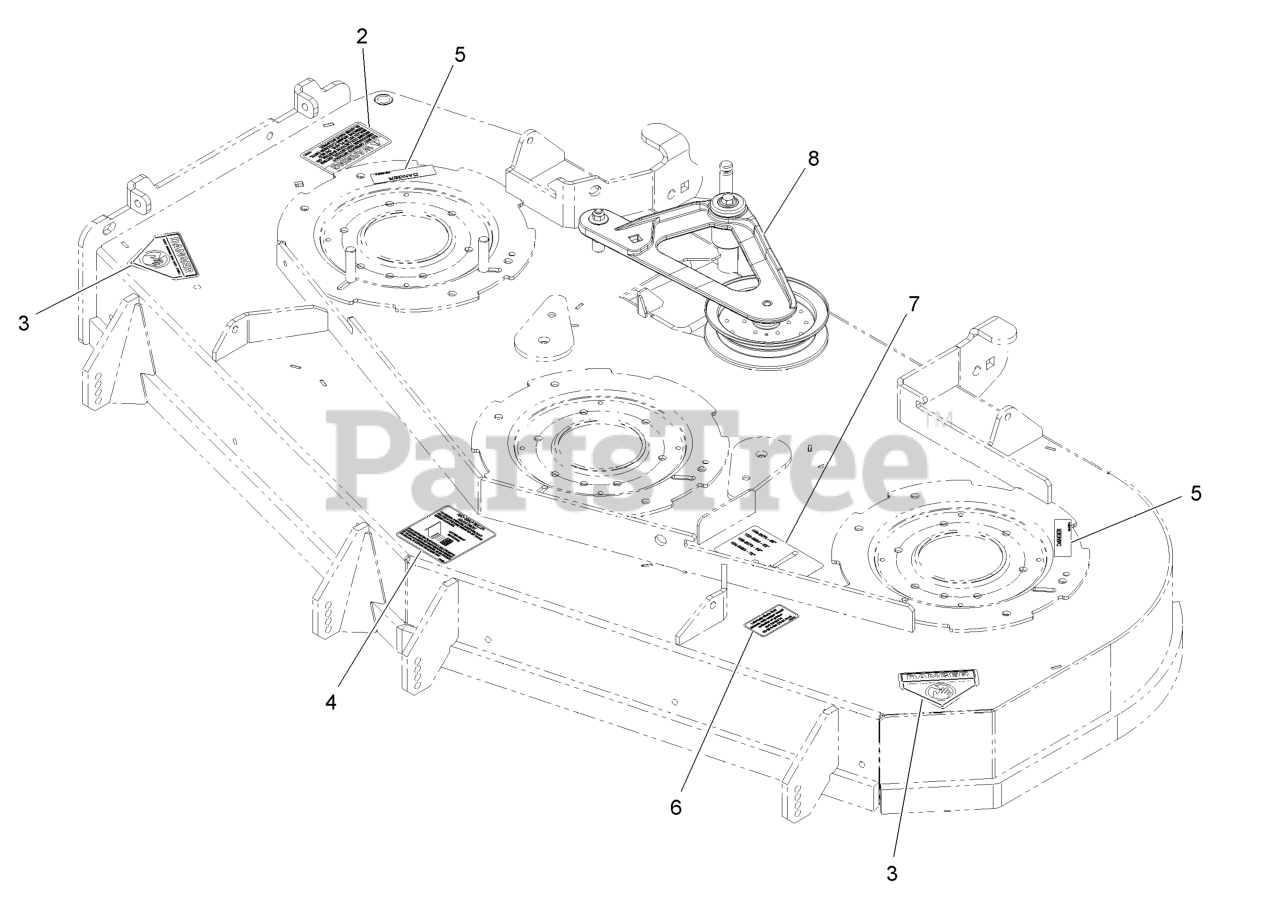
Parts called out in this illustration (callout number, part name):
2	DECAL-WARNING, DISCHARGE
3	DECAL-DANGER
4	DECAL,ANTISCALP
5	DECAL-COVER, MISSING
6	DECAL,BOLT TORQUE
7	DECAL,BELT ROUTING
8	DECK IDLER ASM
